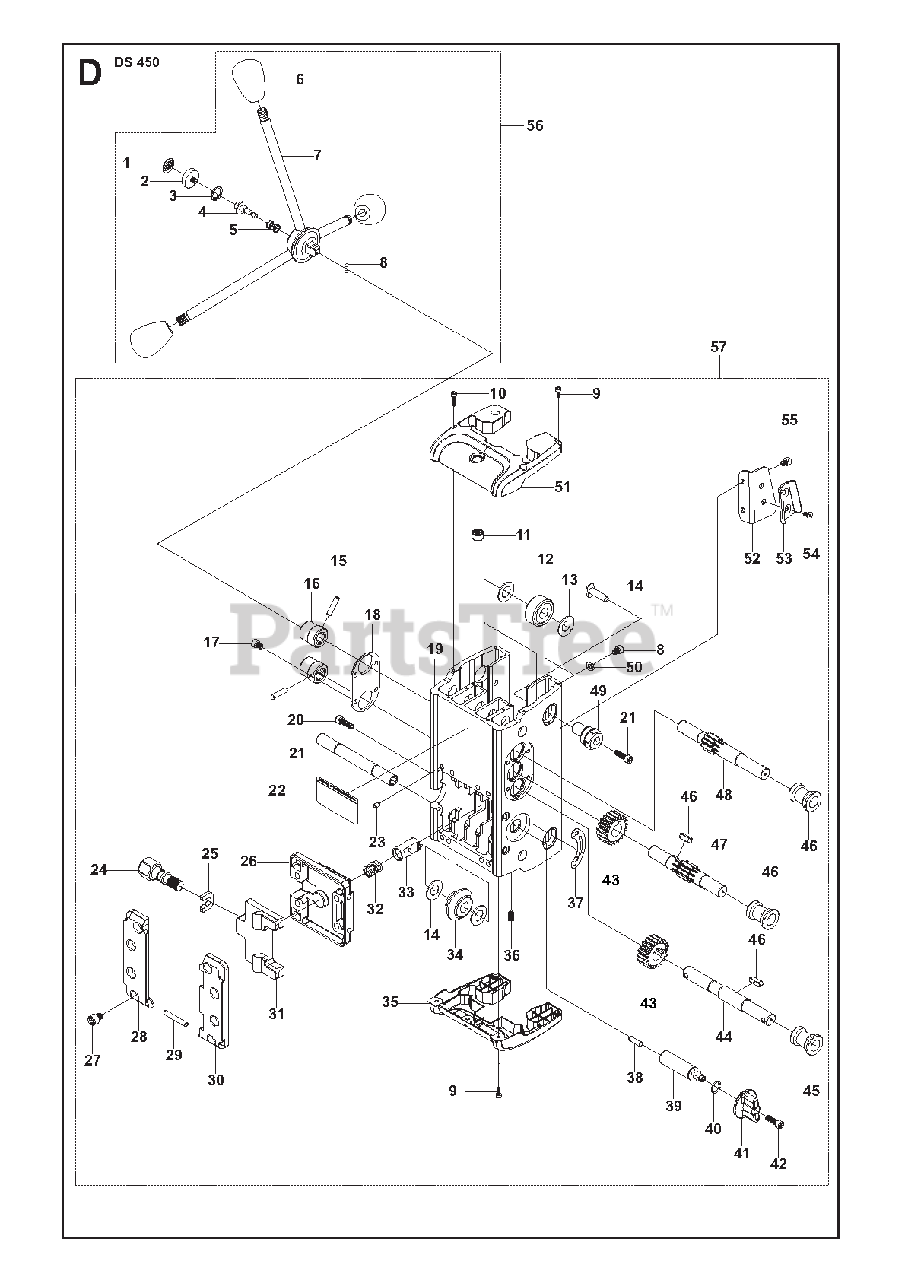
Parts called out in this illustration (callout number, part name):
15	PARALLEL PIN
20	SCREW IHSCM
23	PARALLEL PIN
56	CRANKSHAFT ASSYONLY US
